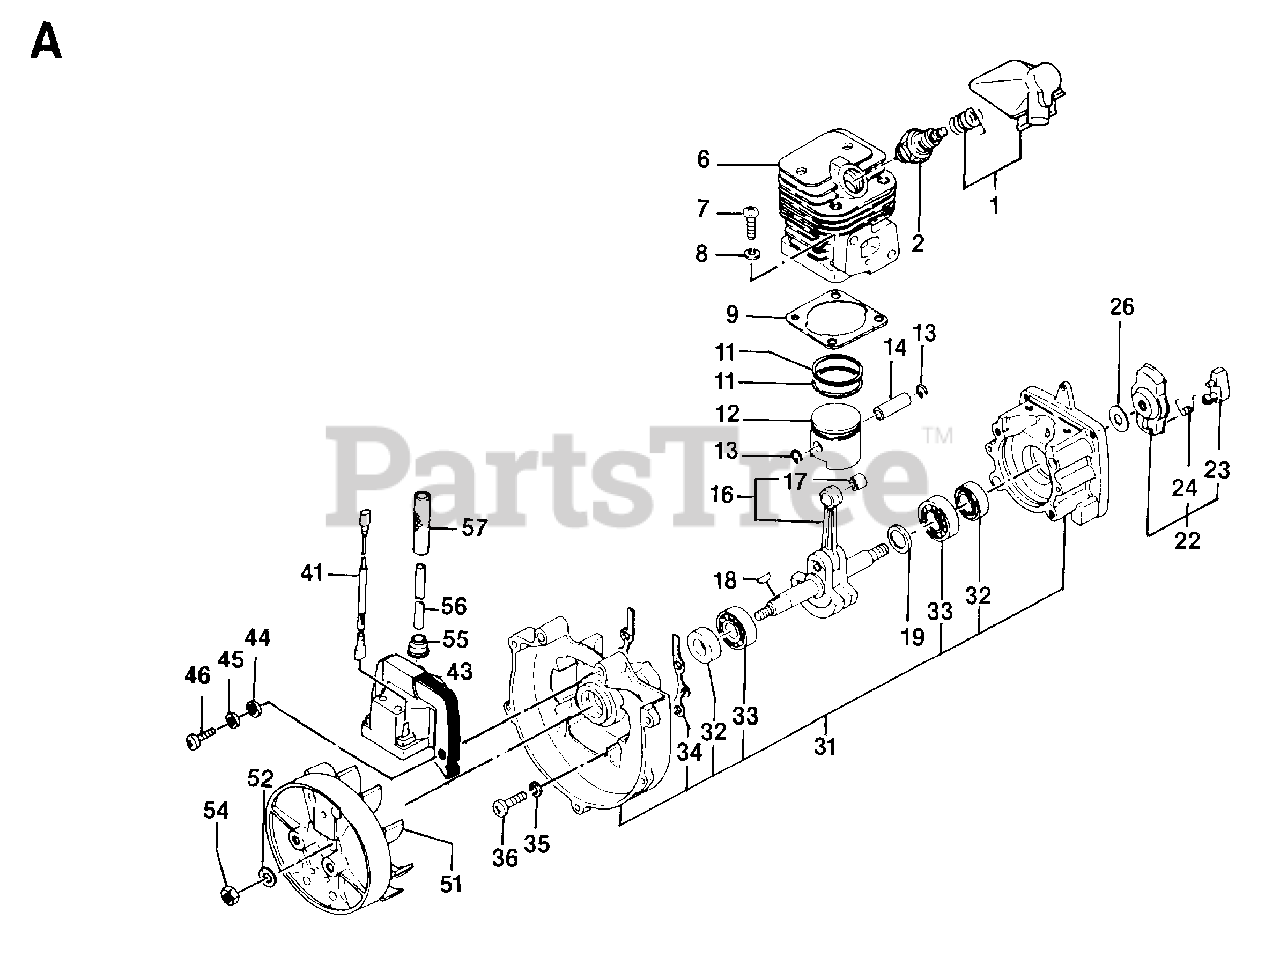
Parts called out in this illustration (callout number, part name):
23	SCREW MC6S 4X8
24	SPRING WASHER 4.1X7.1
43	WASHER
44	SPRING WASHER
58	WASHER
59	SPRING WASHER
